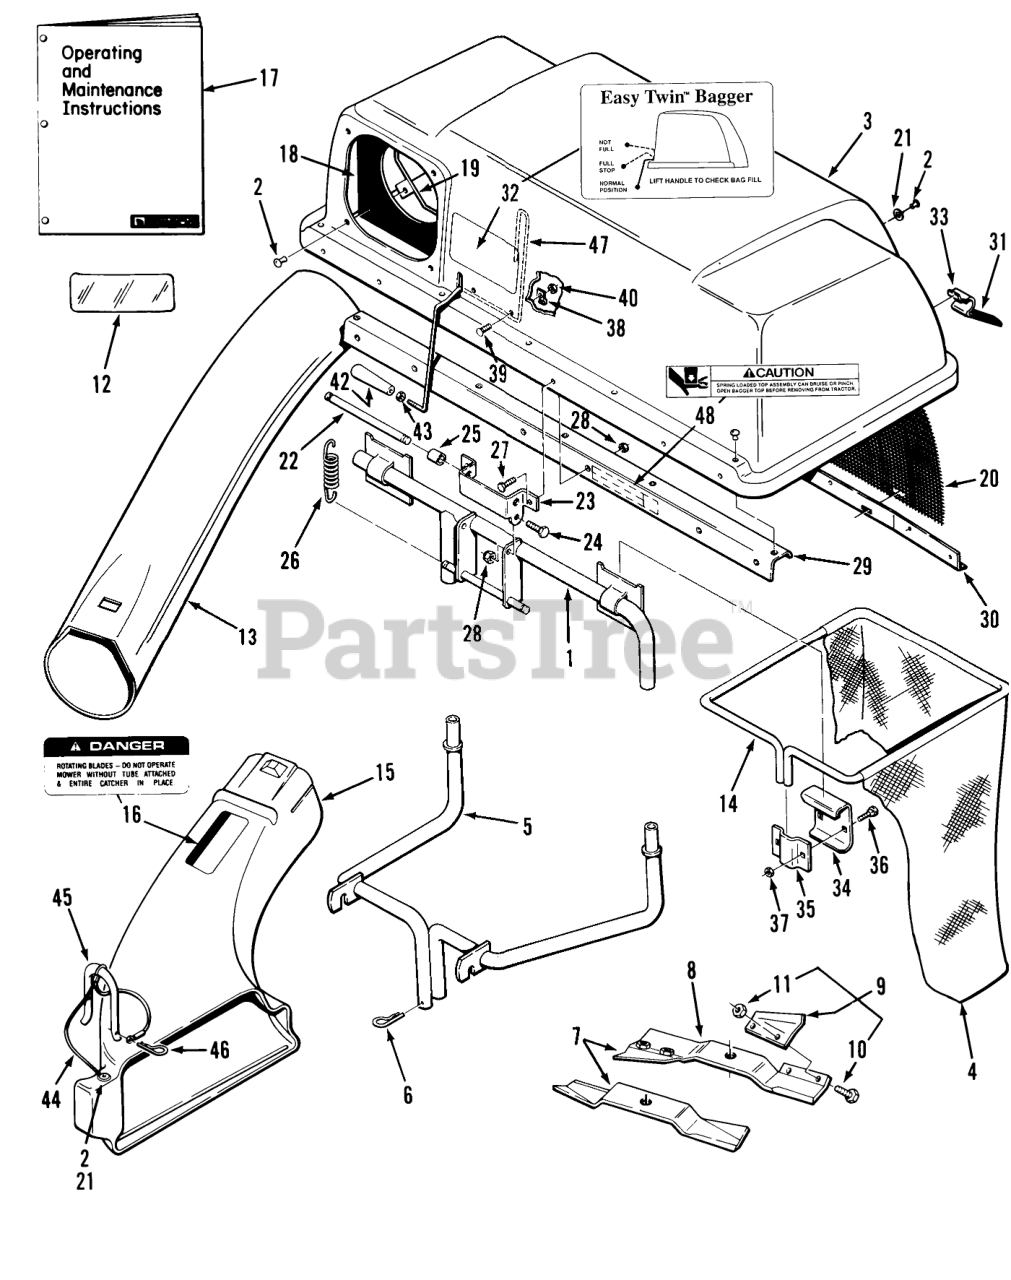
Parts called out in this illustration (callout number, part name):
1	FRAME ASM
2	RIVET-BLIND
3	TOP-BAGGER
4	BAG-18" DEPTH
5	ASM-QUICK ATTACH B
6	Hairpin
7	Blade Kit (includes LH blade, RH blade with tabs)
8	High Lift Blade (includes item 9) RH side
9	Lift Tab Kit (includes items 10 & 11)
10	BOLT 5/16-18X5/8
11	NUT-LOCK 5/16-18
12	DECAL-OVERLAY
13	CHUTE-BAGGER (L)
14	Bag Frame
15	Discharge Elbow (includes items 16 & 44 installed)
16	DECAL-DANGER
17	Operating and Maintenance Instructions
18	Chute Seal
19	CLAMP-SEAL
20	SCREEN-BAGGER
21	Washer
22	PIN-SPRING
23	HINGE-BAG TOPB
24	Bolt
25	SPACER
26	SPRING-EXTENSION
27	BOLT
28	NUT
29	Bagger-Stiffener
30	SUPPORT-SCREEN B
32	Decal-Full Bag Test
33	Latch-Bag
34	Bag Hanger
35	Clamp
36	Bolt
37	Nut
39	Screw
40	Nut
42	HANDLE-TAPERED
43	Nut
44	LANYARD-ELBOW LATCH
45	LATCH-ELBOW
46	Hairpin Cotter
47	FEELER-FILL, BAG
48	DECAL-CAUTION
